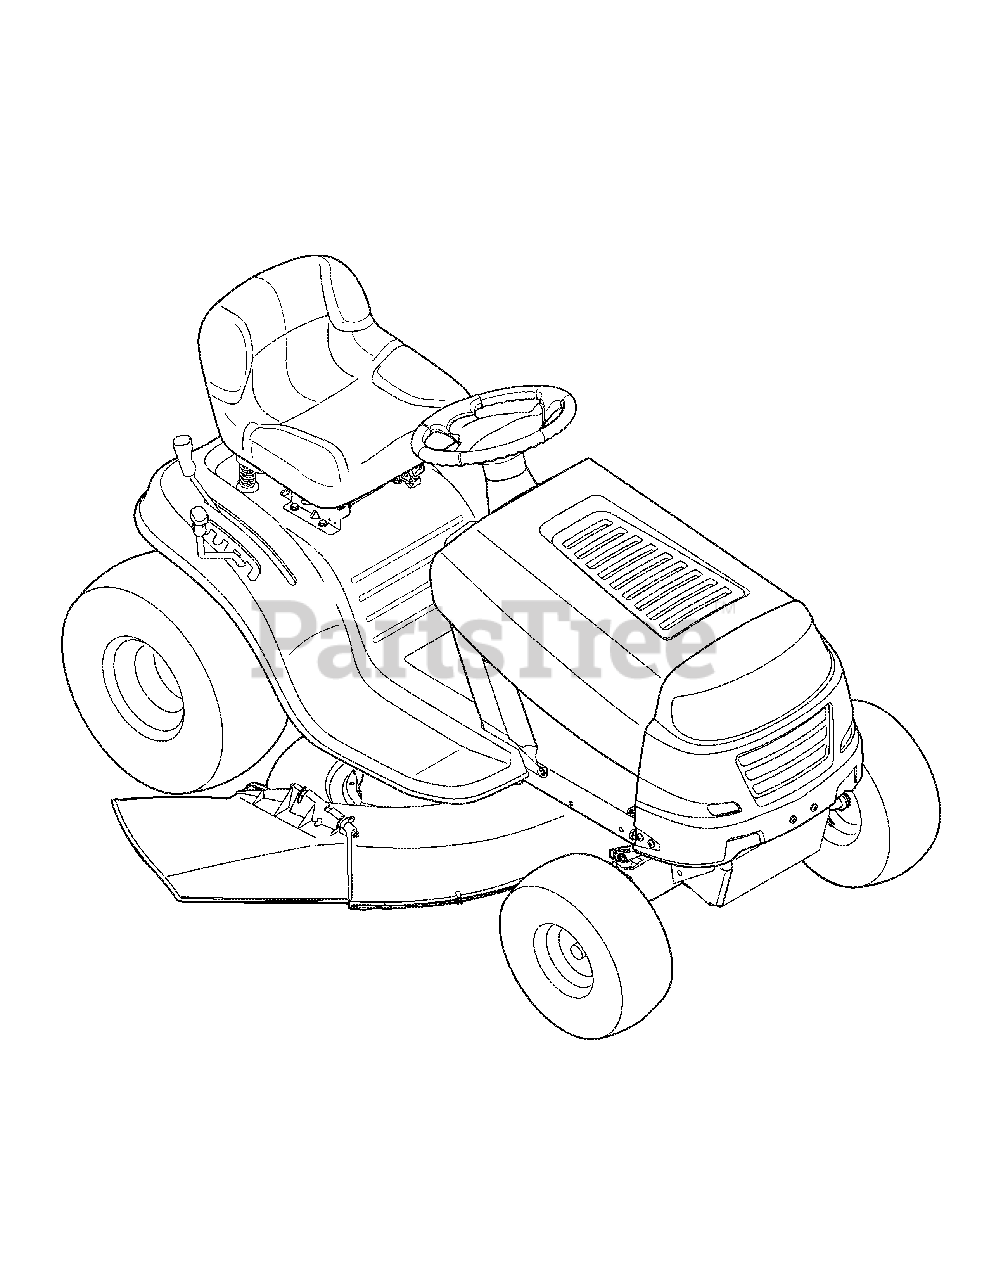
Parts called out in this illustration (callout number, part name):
NA	OIL FILTER
NA	ENGINE TO DECK BELT
NA	DECK WHEELS
NA	WATER NOZZLE ADAPTER
